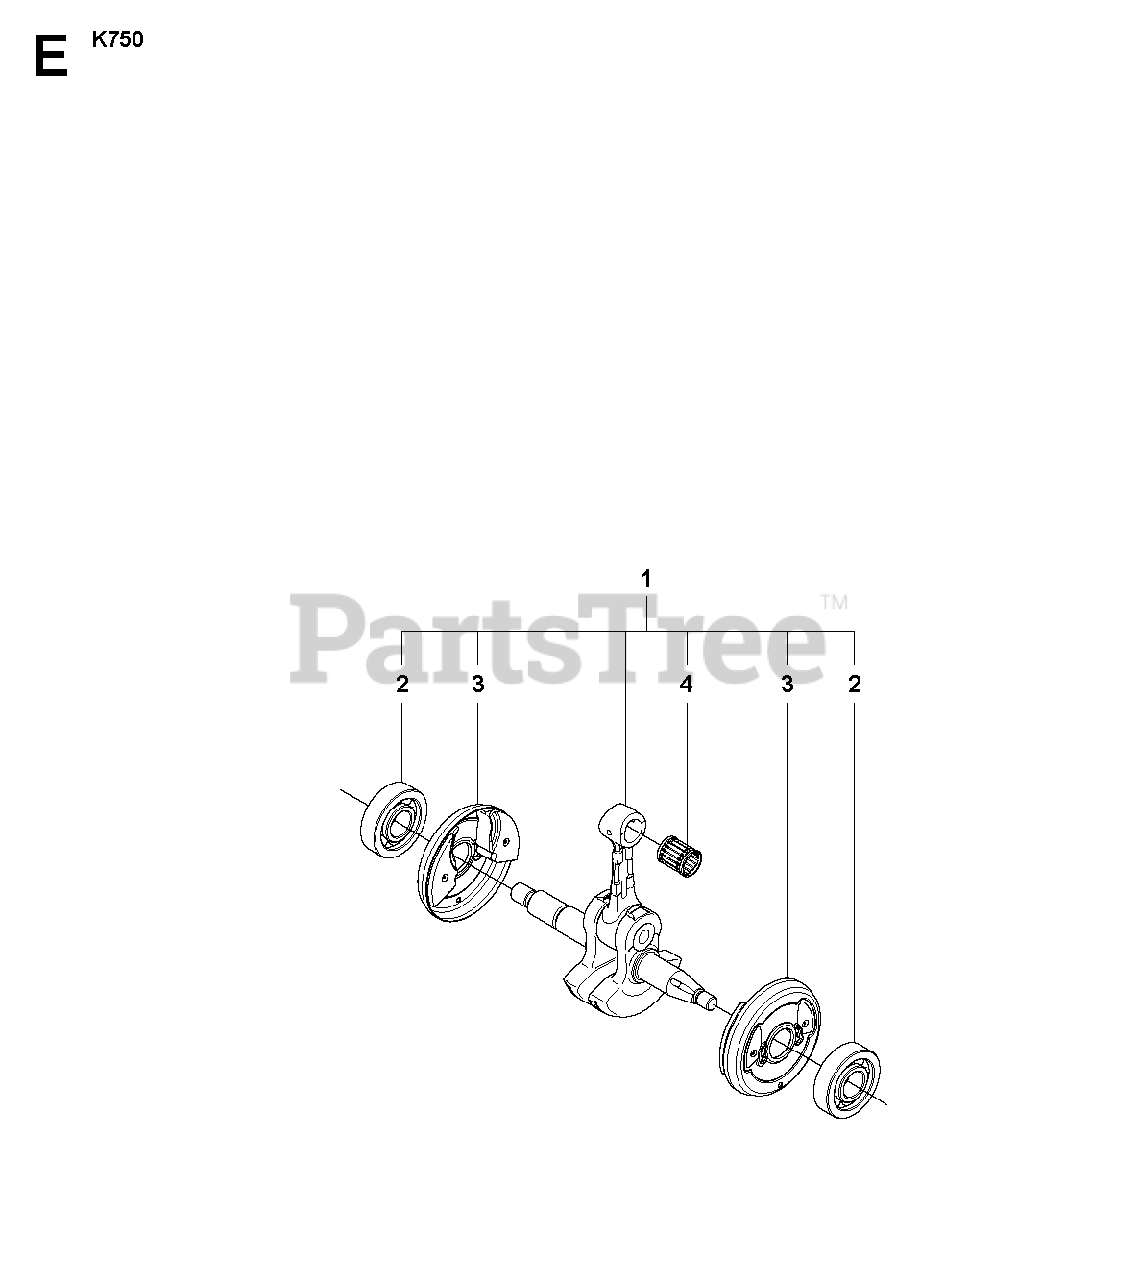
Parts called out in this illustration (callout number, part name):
1	CRANKSHAFT ASSYIncl. 2 - 4
2	BALL BEARING
4	NEEDLE BEARING
